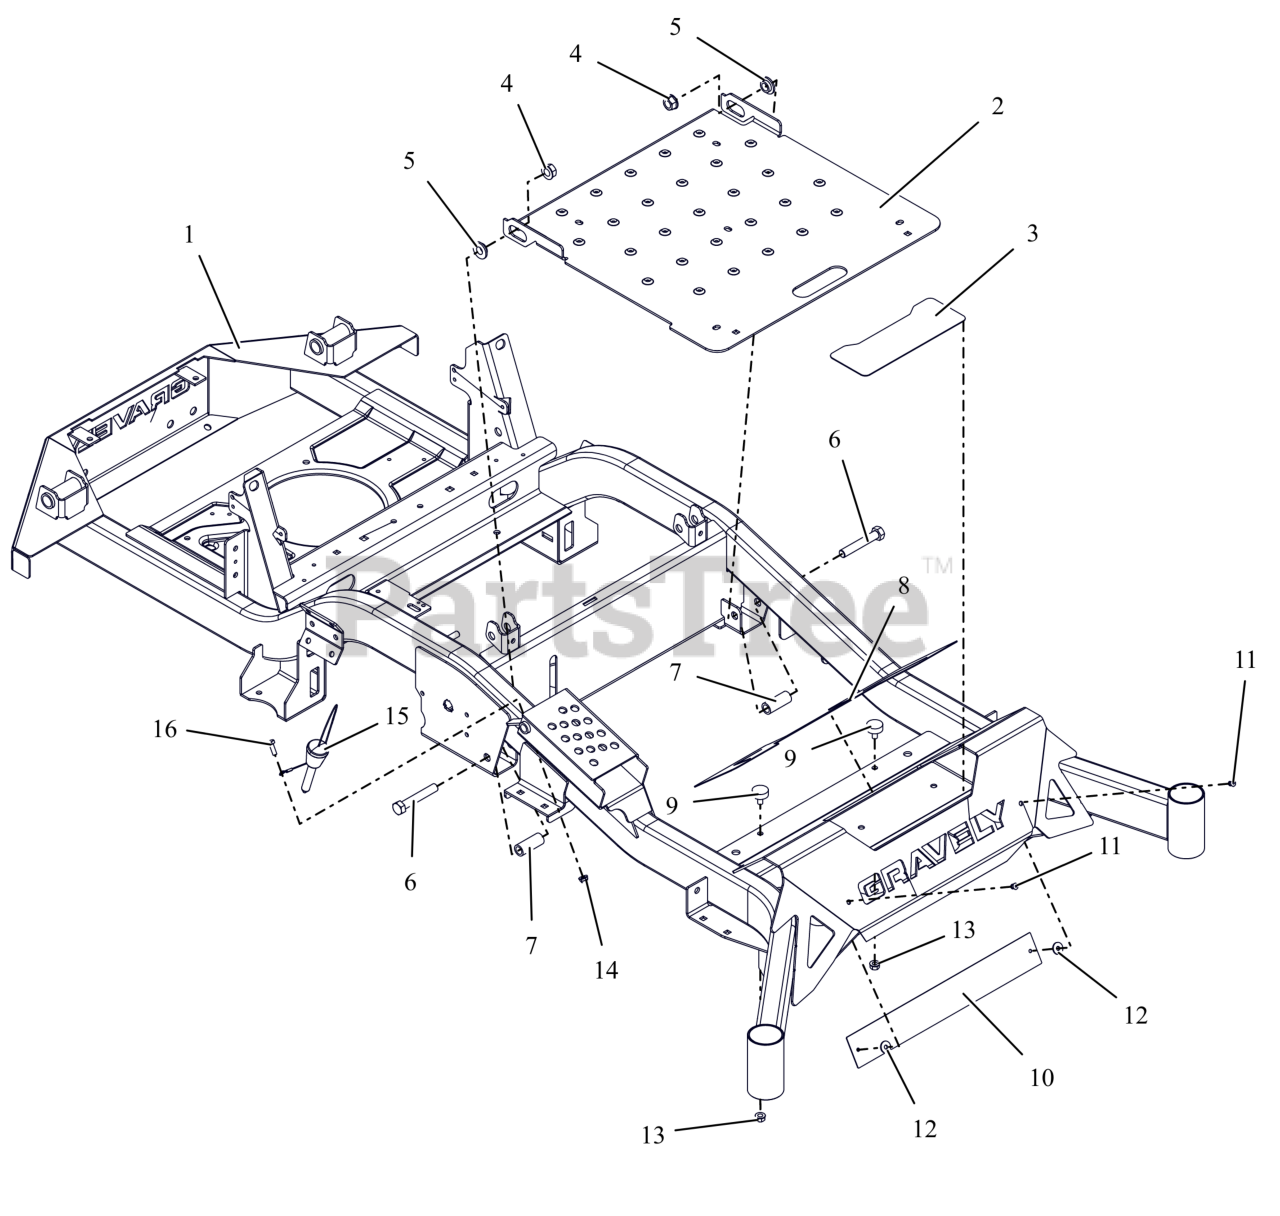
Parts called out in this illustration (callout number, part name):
1	WLDMT, MAIN FRAME -HD 60 (RED)
2	KIT,ACCESS PANEL W/DECALS-RED
3	GRIP, STEP
4	NUT-LK-TOP-FLG .500-13 GF ZCC
5	BSHG-FLG .515X.750X.310X1.120
6	BLT, HEX .50-13X3.00 G5 ZCC
7	SPACER, .515X.75X1.83
8	GRIP, FRONT
9	BUMPER, RUBBER
10	PLATE, BACK FOOT-REST XL
11	RIVET, .1875 AL/AL .126-.250
12	WSHR, RBR W/ADHESIVE .25X.75X.06
13	NUT,SPNLK-FLG .31-18 G5 ZCC
14	NUT,NYL-FLG .25-20 GF ZCC
15	PIN- MAGNETIC .50X2.70
16	BLT, HEX .25-20X.75 G5 ZCC
